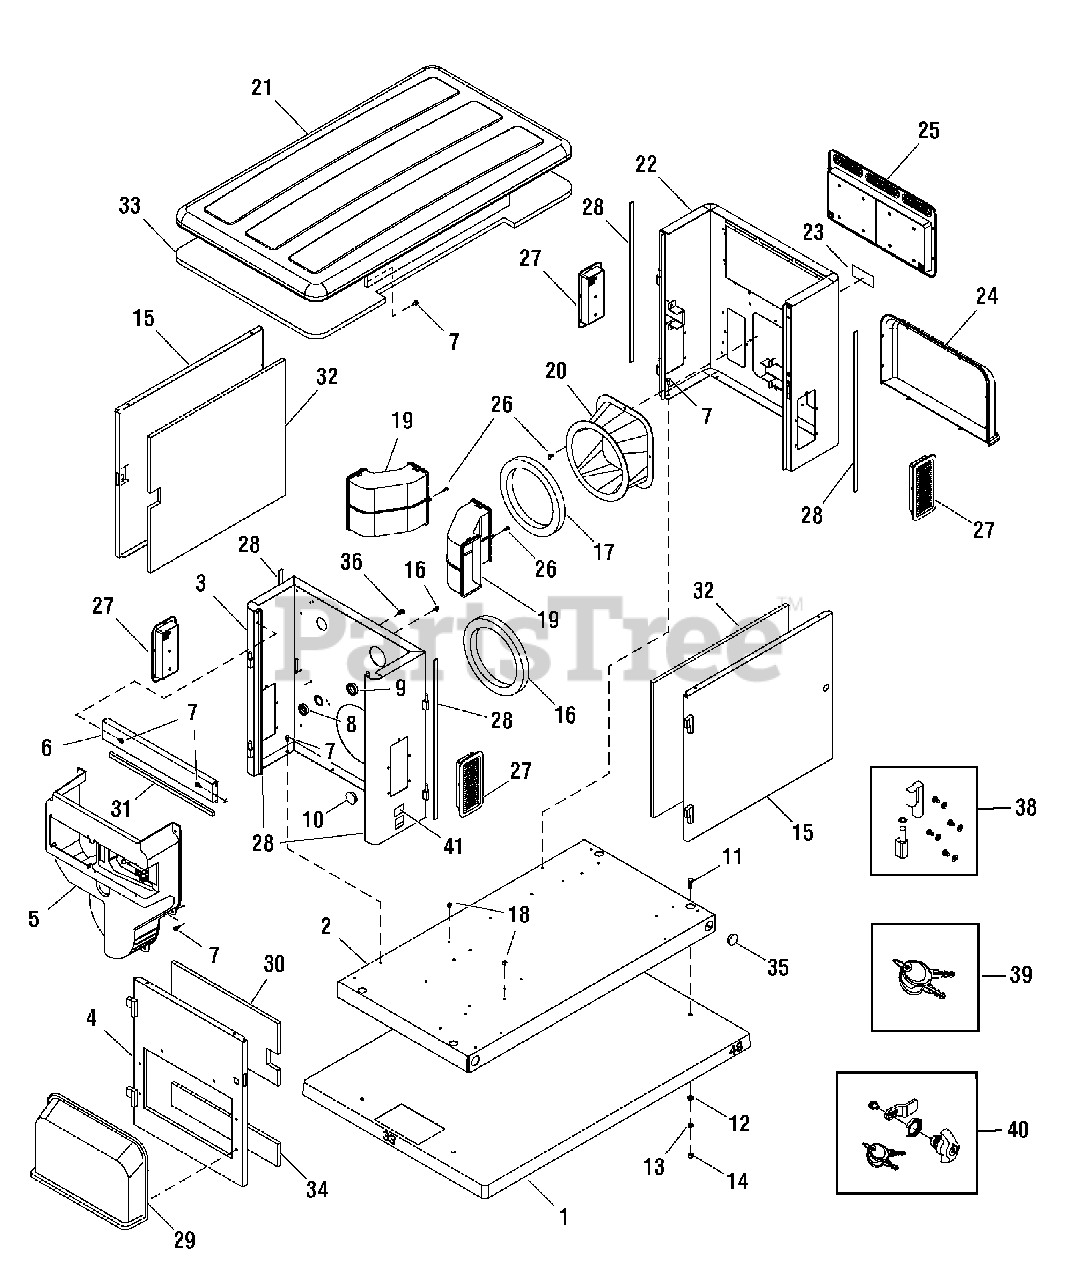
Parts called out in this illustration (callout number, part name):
3	BULKHEAD, Engine
7	BOLT
11	* CAPSCREW, Hex Head, 3/8-16 x 1
12	* WASHER, Flat, 3/8-M10
13	* WASHER, Lock ,3/8
14	* NUT, 3/8-16
16	SEAL, Foam
20	ADAPTER, Engine
22	BULKHEAD, Alternator
24	COVER, Air Intake
29	COVER, Air Intake
41	DECAL
